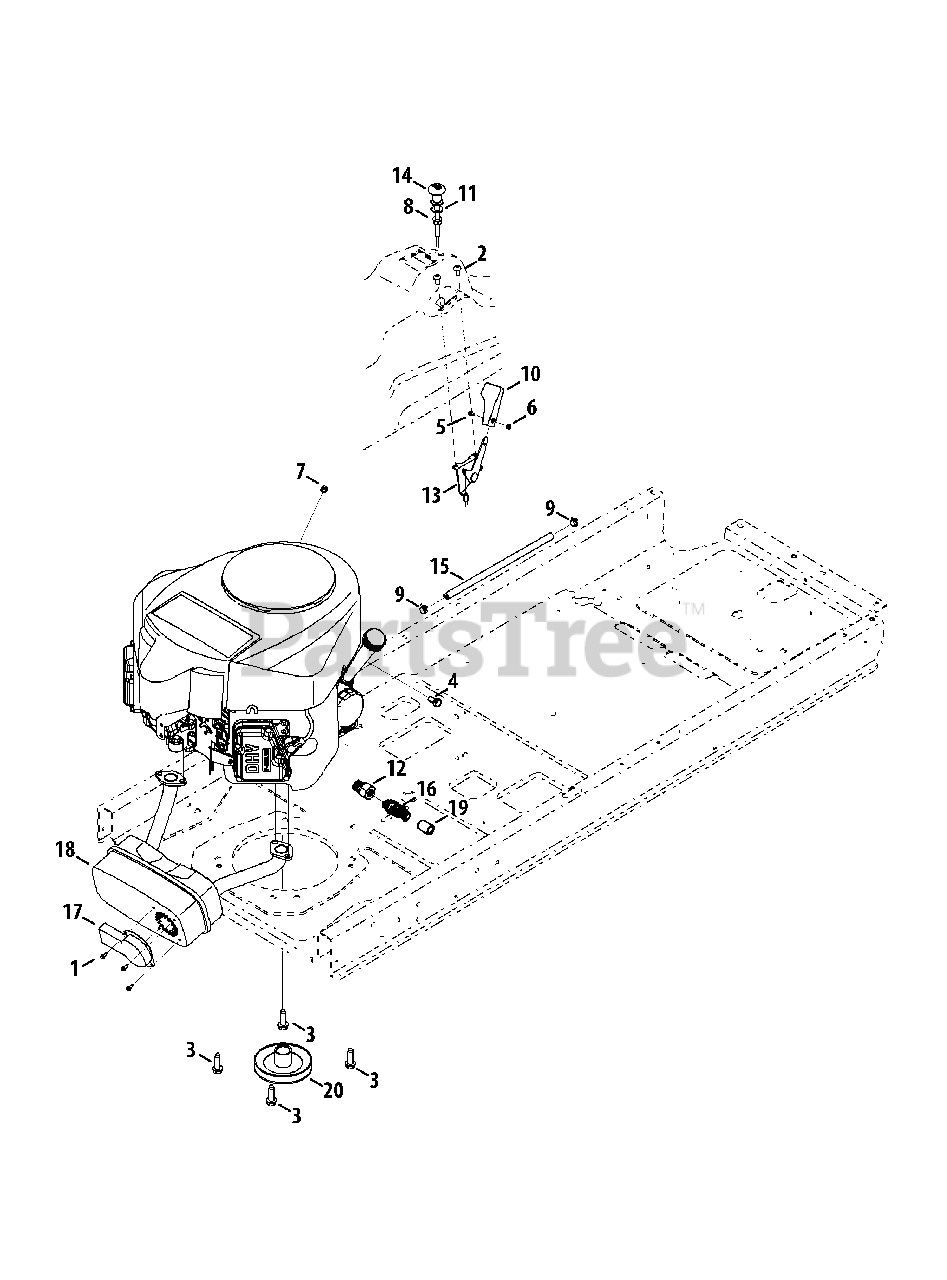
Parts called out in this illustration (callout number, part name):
1	Hex Washer Screw, #8-18 x .500
2	Screw, 1/4-20 x .50
3	Tap Screw, 3/8-16 x 1.25
4	Hex Screw, M8-1.25 x 16
5	Screw, #8-32 x .375
6	Hex Nut, #8-32
7	Flange Lock Nut, 1/4-20
8	Flange Lock Nut, 3/8-16
9	Hose Clamp, .490 Dia.
10	Throttle Control Knob
11	Flat Washer, .406 x .875 x .059
13	Throttle Cable
14	Choke Cable
15	Fuel Hose, 1/4
17	Deflector, Muffler, Long
18	Kawasaki Twin Muffler
19	Oil Drain Hose
20	Engine Pulley
